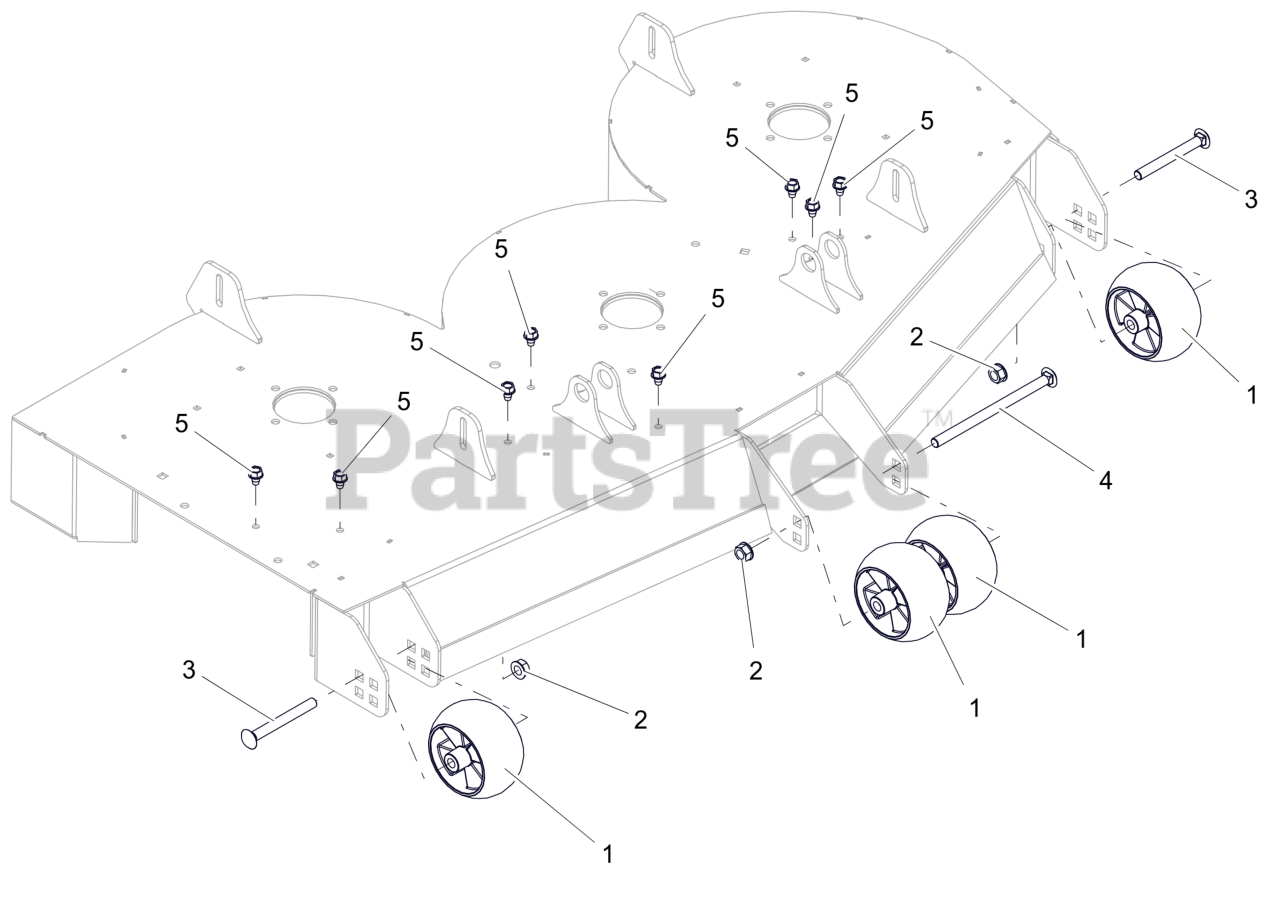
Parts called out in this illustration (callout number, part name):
1	WHEEL, ANTI SCALP - 5X3 CTR W/RIBS
2	NUT-LK-CTR-FLG .500-13 GG ZCC
3	BLT,RHNS .50-13X4.50 G5 ZCC NS
4	BLT,RHSN .50-13X8.00 G5 ZCC NS
5	SCR,TAP .375-16X.50 HWH TR ZCC
